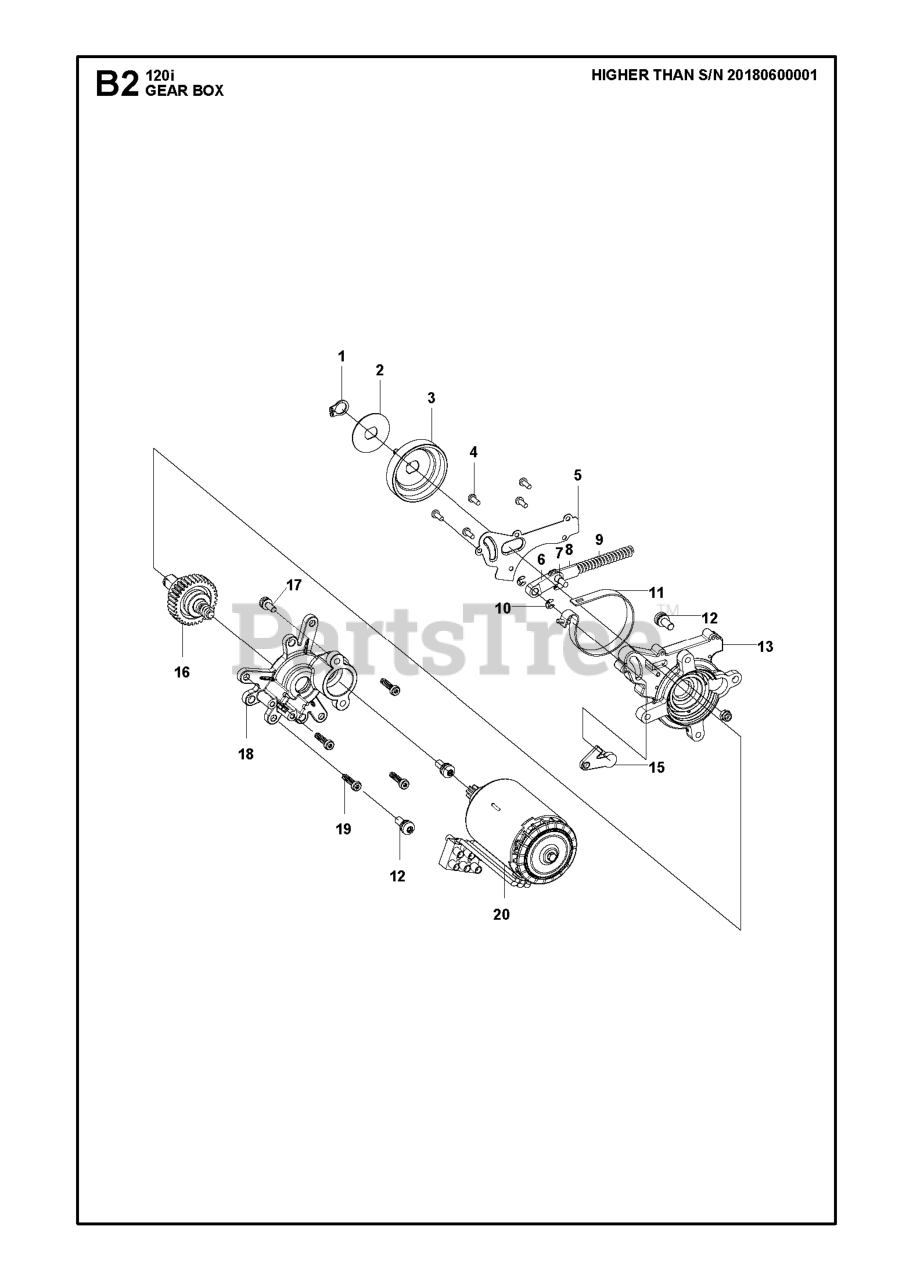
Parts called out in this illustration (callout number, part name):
3	SPROCKET CHAIN 6 TOOTH
4	SCREW M3X8 MACHINE SCREW
5	COVER PLATE BRAKE
6	PLATE JOINT
7	PEN BRAKE SYSTEM
8	PLATE BRAKE
9	BRAKE SPRING
10	CLAMP FOR BRAKE SYSTEM
11	BRAKE BAND
12	SCREW M5X13TOR X MACHINING SCR
13	GEARBOX BOTTOM 36V
14	NUT LOCKING NUT
15	DRIVE LINK DRIVE LINK
19	SCREW ST4X16
